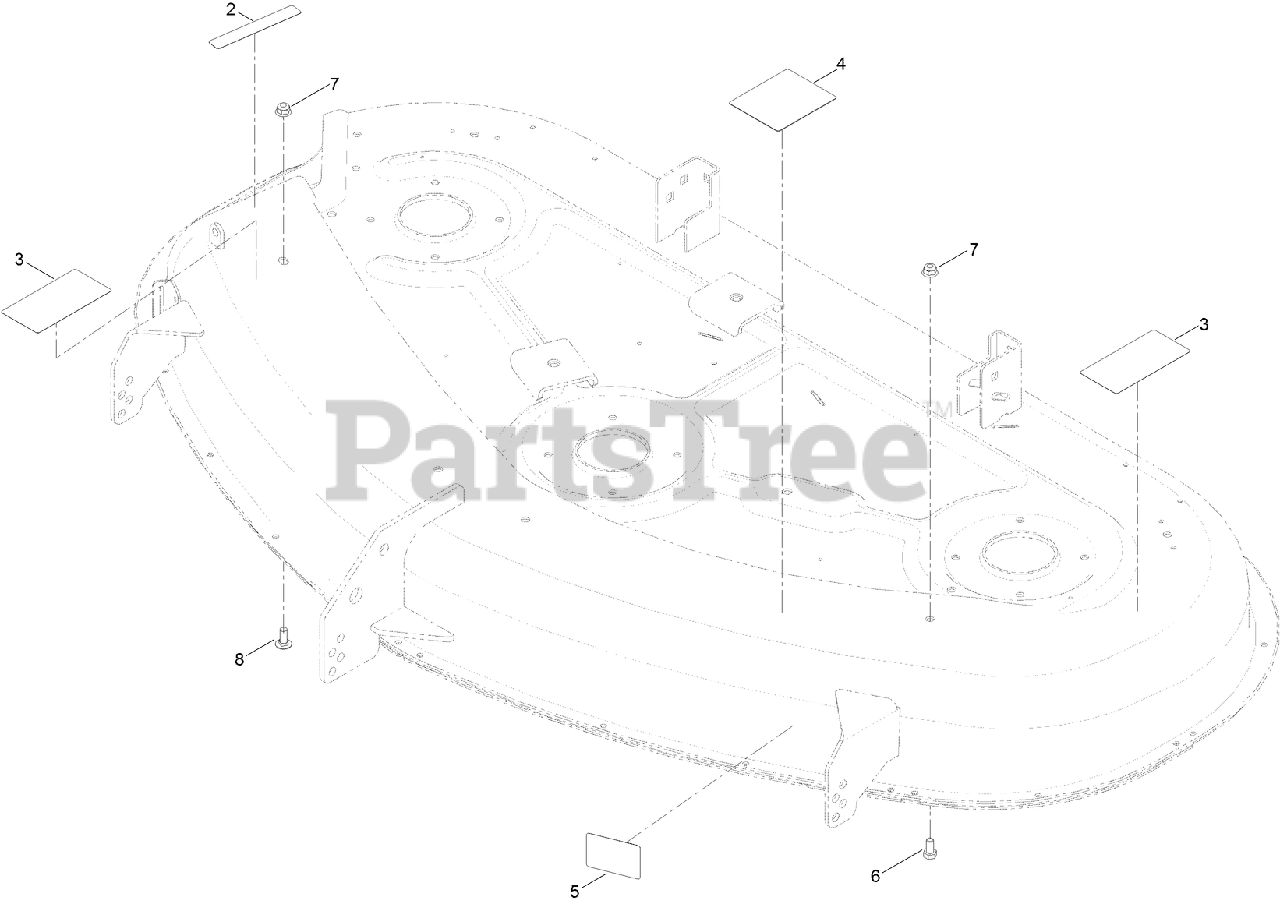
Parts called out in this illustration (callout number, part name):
2	DECAL-DANGER
3	DECAL-DANGER, DECK
4	DECAL-ROUTING, BELT
5	DECAL-SCALP, ANTI
6	SCREW-HH
7	NUT-HF, NI
8	SCREW-CARR
